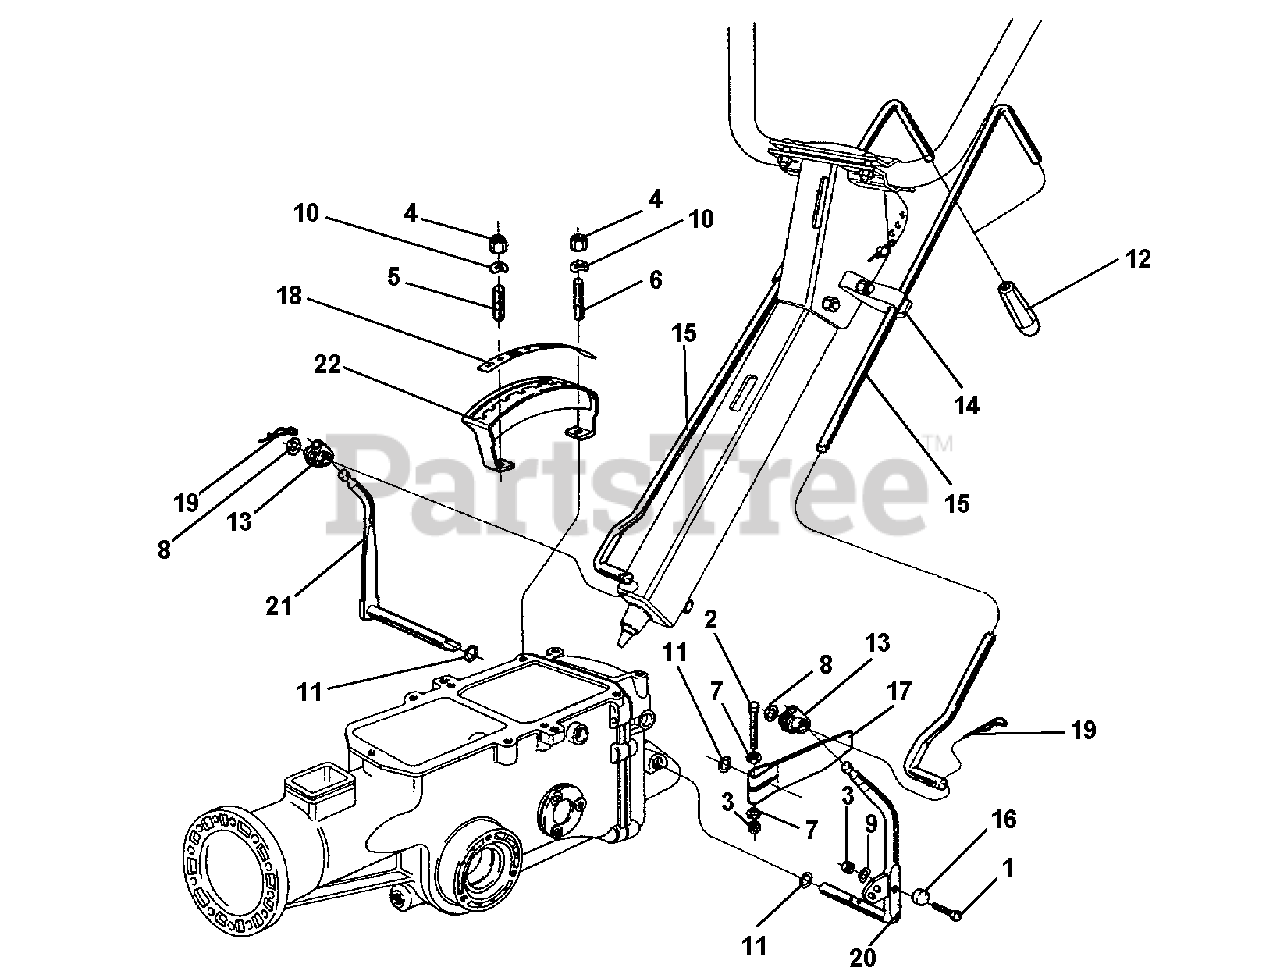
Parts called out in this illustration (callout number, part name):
1	SCREW M6 X 25
2	SCREW M6 X 40
4	NUT, SELF LOCKING M8
5	STUD M8 X 38 X 14 X 20
6	STUD M8 X 46 X 16 X 16
7	WASHER, FLAT 6.4
8	WASHER P10.5 X 18
9	WASHER, LOCK 6.4
10	WASHER, LOCK 8.4
11	O-RING 115 11.91 X 2.62
13	JOINT, D 10
14	SUPPORT CONTROL ROD CUT
15	ROD, CONTROL POWER TILLER
17	CONTRAST REVERSE SPEED
18	PLATE, 5 SPEEDS WALKING TRAC
20	P.T.O. LEVER
21	GEARBOX LEVER
